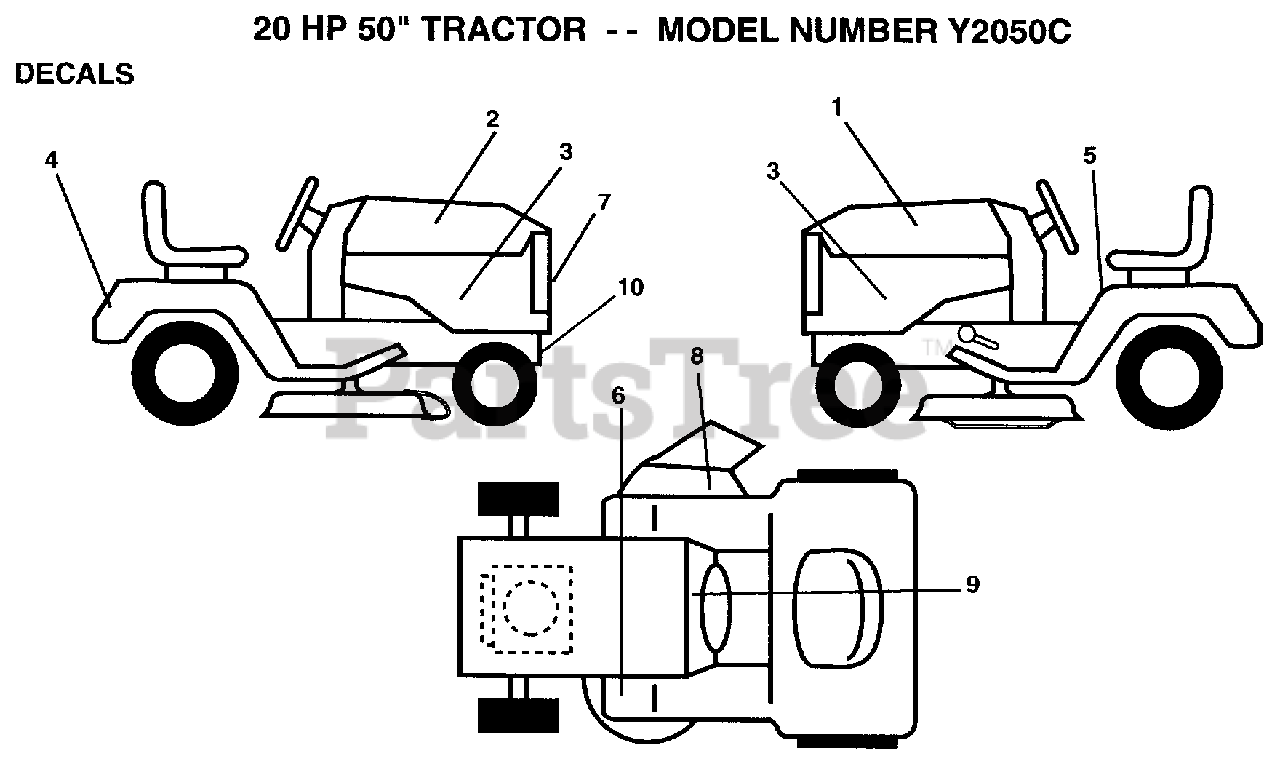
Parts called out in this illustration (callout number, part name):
1	DECAL HOOD LH
3	DECAL.PANEL.SIDE
5	DECAL CAUTION
6	DECAL T
7	DECAL.GRILL.YARDP
8	"DECAL, WARNING"
9	DECAL.DASH.INSTR.
